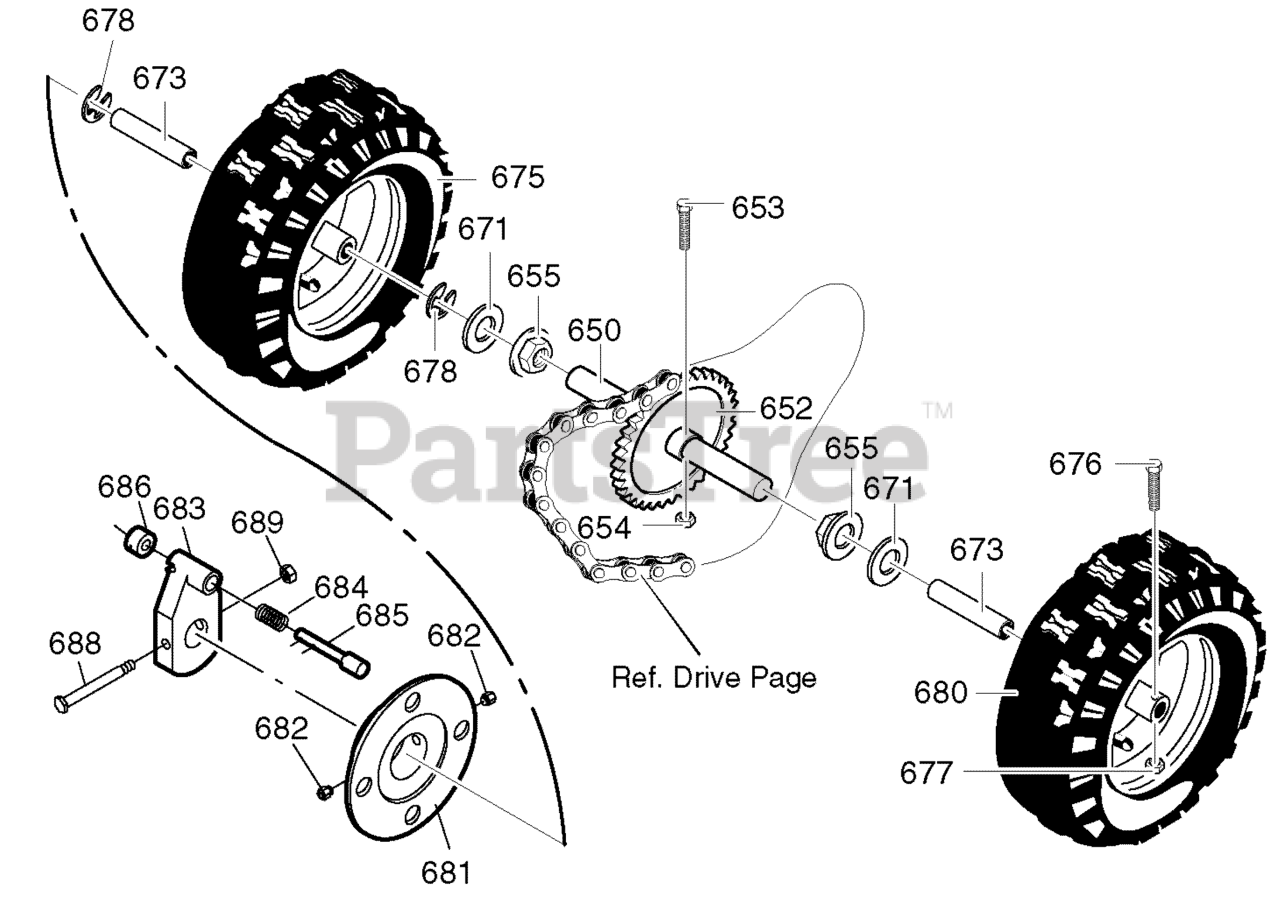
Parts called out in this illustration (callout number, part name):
650	YZ SHAFT, AXLE
652	SPRKT & HUB
653	SCREW, 1/4-20X1.75
654	NUT, 1/4-20 HEX NYLOCK
655	BEARING, AXLE
671	FLATWASHER
673	BUSHING, WHEEL
675	TIRE & RIM, RIGHT
676	SCREW, 1/4-20X1.75
677	NUT, 1/4-20 HEX NYLOCK
678	RING, RET
680	TIRE & RIM, LEFT
681	DISC,WHEEL
682	SCREW
683	HUB, WHEEL LOCK
684	SPRING, COMPRESSION
685	YZ PIN, LOCK
686	KNOB
688	SCREW
